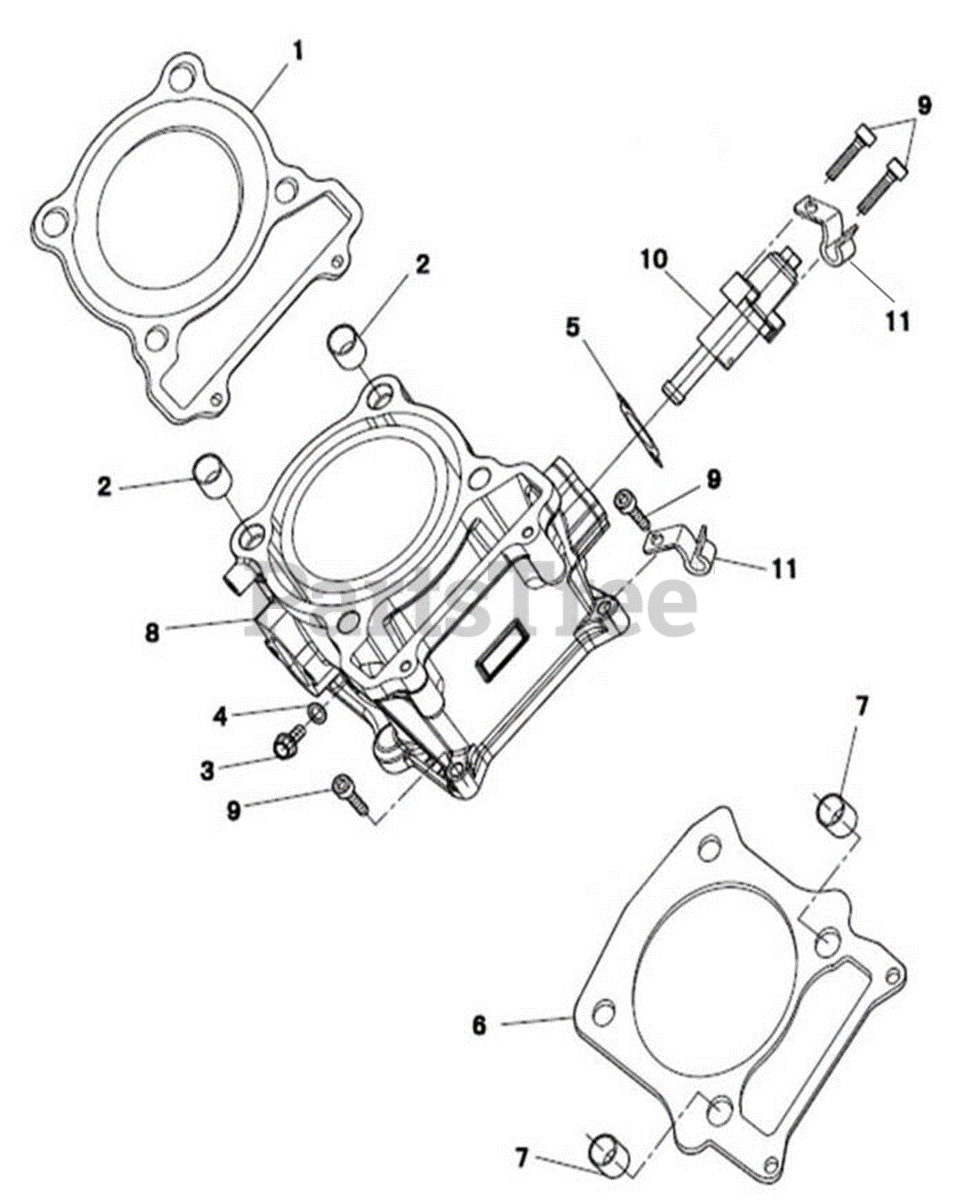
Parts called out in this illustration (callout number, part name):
1	HEAD GASKET
2	DOWEL PIN 12X16
3	HEX FLANGE BOLT M6X12
4	ALUMINUM WASHER 6X12X1.5
5	TENSIONER GASKET
6	CYLINDER GASKET
7	DOWEL PIN 14X16
8	CYLINDER ASSEMBLY
9	HEX HEAD CAP SCREW M6X25
10	TENSIONER ASSEMBLY
11	WIRE CLAMP
